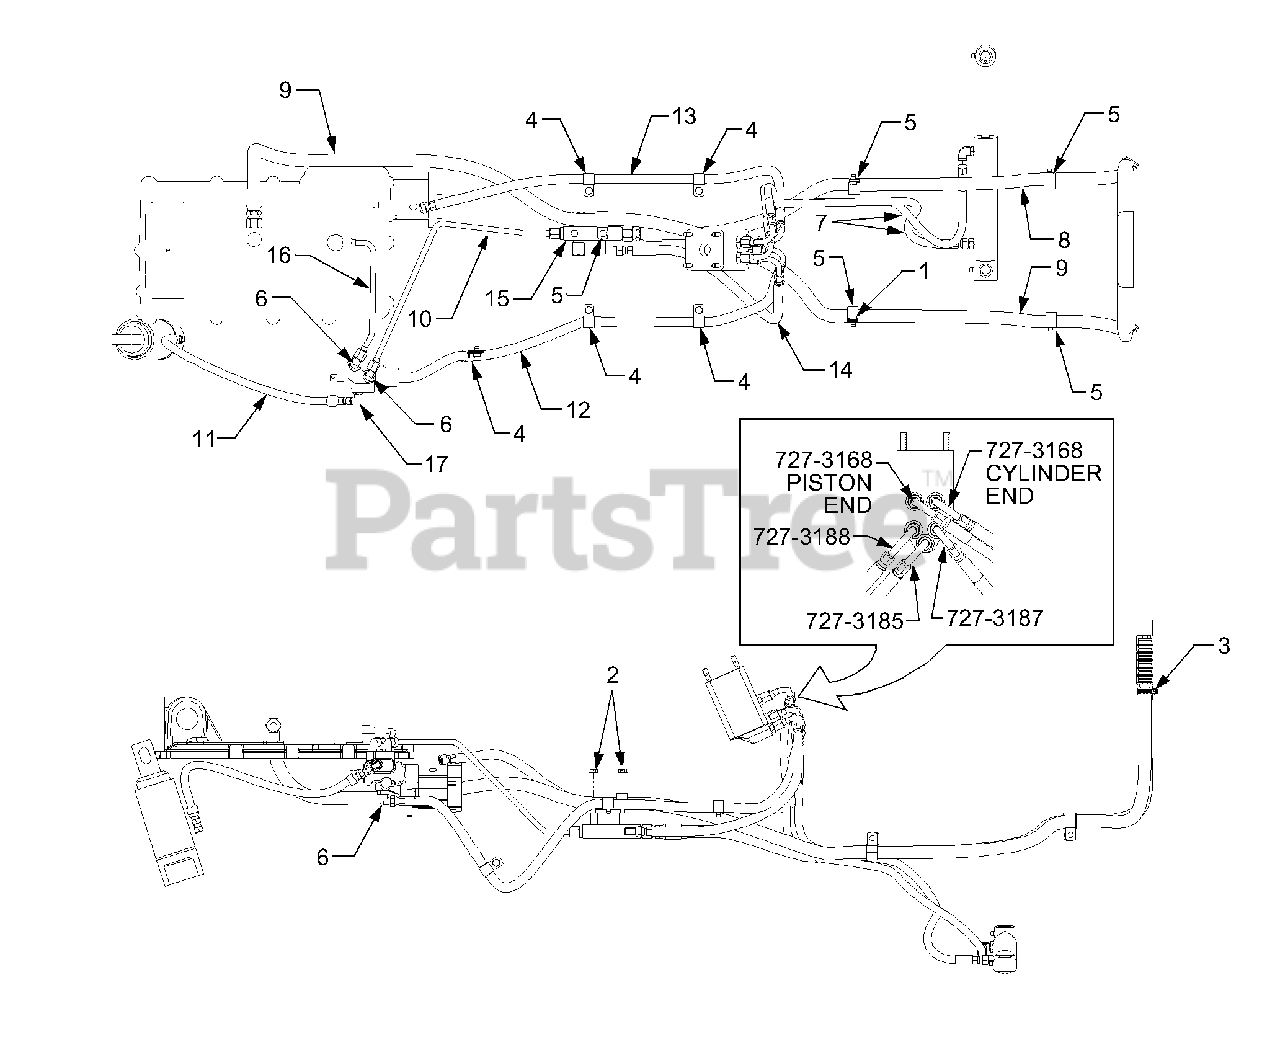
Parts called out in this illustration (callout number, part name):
1	Screw, Hex Wash Hd. Tapp 5/16-18 x .5
2	Nut, Hex Flange Lock, 5/161-18 GR5
3	Clamp, Adjustable Hose
4	Clamp, Hose
5	Clamp, Hose
6	Fitting, 90 Degree
7	Hose, Steering
8	Tube, Oil Cooler Return
9	Hose, Oil Return
10	Tube, Lift Return Line
11	Hose, Lift Cylinder
12	Hose, Lift Inlet
13	Hose, Steering Pressure
14	Hose, Steering Tank
15	Manifold, Return
16	Tube, Cylinder Return
17	Fitting, 90 Degree
